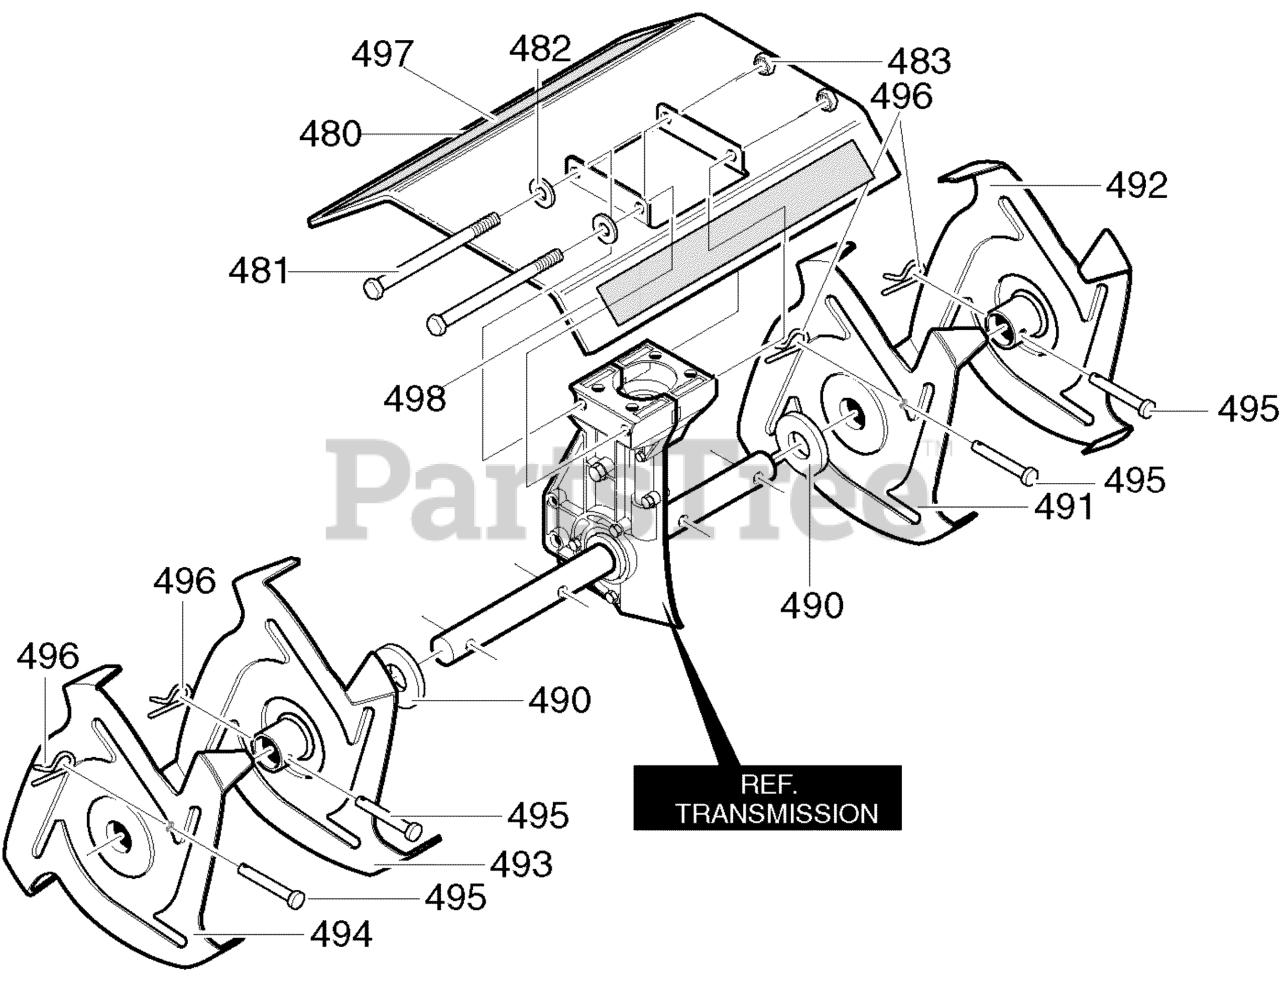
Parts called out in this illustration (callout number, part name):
480	Shield, Tine
481	Screw, 1/4-20x5
482	Flat washer
483	Nut, 1/4-20
490	Washer, Felt
491	Tine Assy. Inner LH
492	Tine Assy. Outer LH
493	Tine Assy. Inner RH
494	Tine Assy. Outer RH
495	Clevis Pin
496	Hair Pin
497	Decal, Caution
498	Decal, Tine Shield
